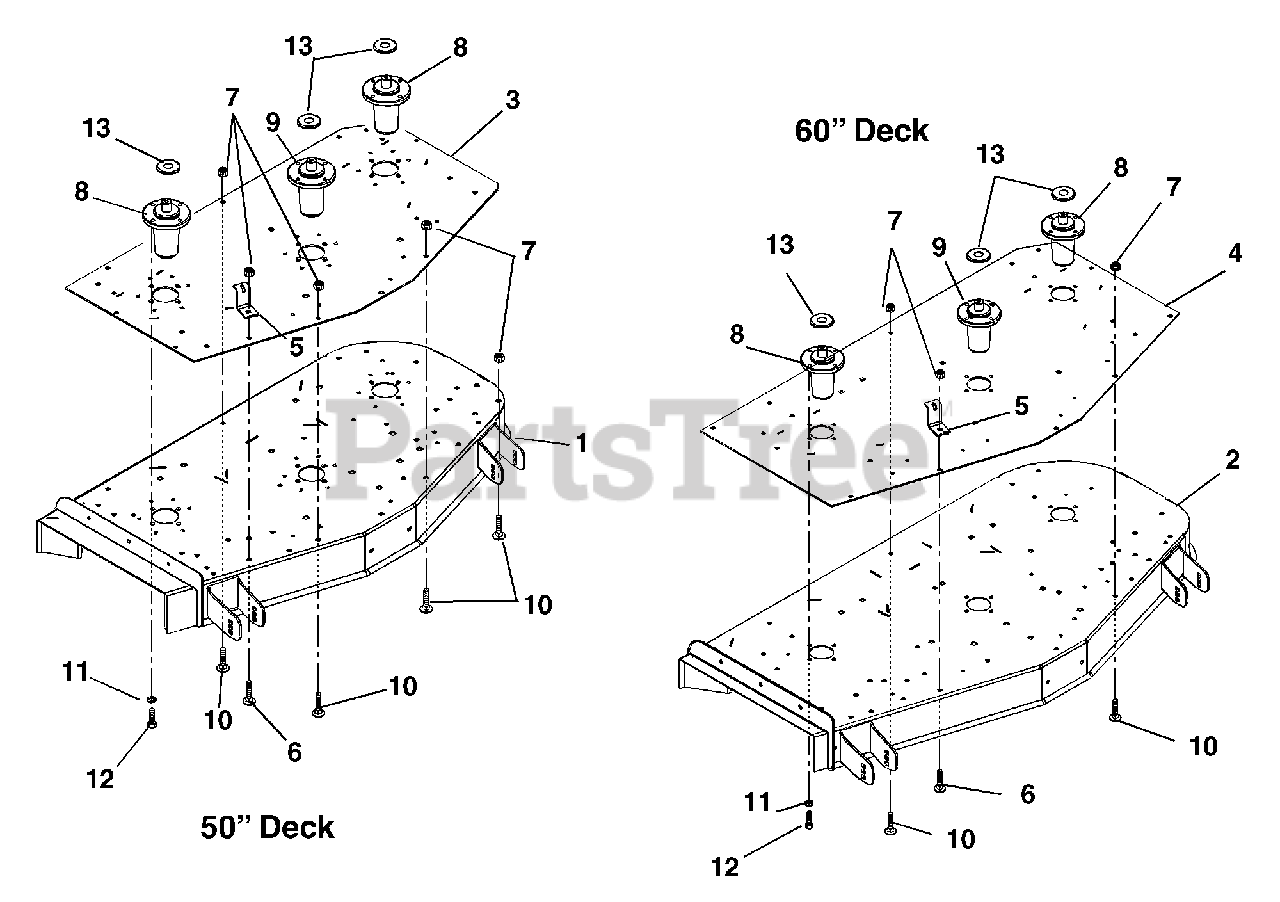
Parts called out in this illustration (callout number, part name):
1	Weldment, 50" Deck (Side Discharge)
2	Weldment, 60" Deck (Side Discharge)
3	Plate, 50" Reinforcement
4	Plate, 60" Reinforcing
5	Anchor, Spring
6	Bolt-Round Head Square Neck .38-16 x 1.25 Grade 2
7	Nut-Locking-Nylon .38-16 (50" Deck)
7	Nut-Locking-Nylon .38-16 (60" Deck)
8	Assembly, Spindle L-Hub
9	Spindle Assembly (Center)
10	Bolt-Round Head Square Neck .38-16 x 1.00 Grade 2 (50" Deck)
10	Bolt-Round Head Square Neck .38-16 x 1.00 Grade 2 (60" Deck)
11	Washer-Locking .38 x .094
12	Bolt-Hex .38-16 x 1.00 Grade 5
13	Slinger-Dust
